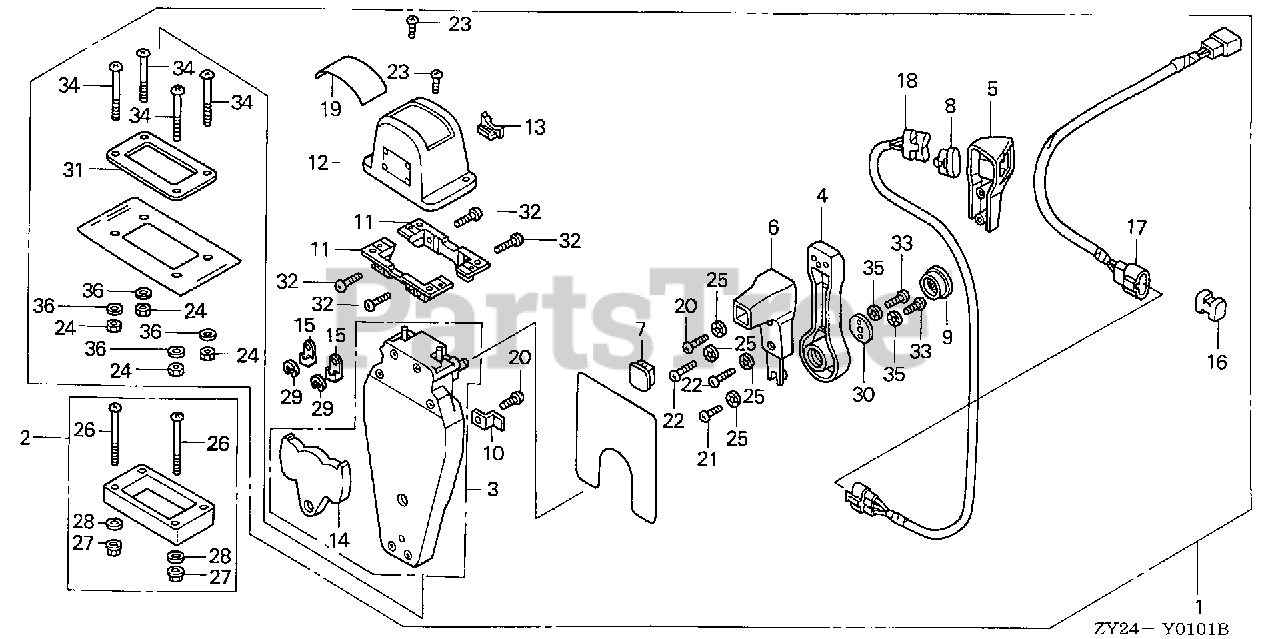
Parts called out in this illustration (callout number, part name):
1	BOX KIT, REMOTE CONTROL (TOP MOUNT SINGLE)(L)
2	SPACER KIT, REMOTE CONTROL BOX (TOP MOUNT SINGLE)
3	HOUSING ASSY., R. (INNER) (TOP MOUNT)
4	HANDLE, REMOTE CONTROL
5	COVER, R. GRIP
6	GRIP, REMOTE CONTROL HANDLE
7	CAP, GRIP
8	CAP, SWITCH
9	BUTTON, THROTTLE
10	PLATE, CABLE CLAMP
11	BRACKET, REMOTE CONTROL HOUSING
12	HOUSING, REMOTE CONTROL BOX
13	HOUSING, LEAD
14	PLATE, DWELL
15	TERMINAL, CABLE
16	SPACER, CABLE CLAMP
17	SUB-HARNESS ASSY., POWER TRIM-TILT (B)
18	SWITCH ASSY., POWER TRIM-TILT (B)
19	MARK, REMOTE CONTROL (SINGLE)
20	SCREW, PAN (5X16)
21	SCREW, PAN (5X10)
22	SCREW, PAN (5X20)
23	SCREW, PAN (4X10)
24	NUT, HEX. (5MM)
25	WASHER, LOCK (5MM)
26	SCREW, PAN (5X65)
27	NUT, FLANGE (5MM)
28	WASHER, PLAIN (5MM)
29	E-RING (6MM)
30	PLATE, HANDLE
31	GASKET, SINGLE
32	SCREW, PAN (5X18)
33	SCREW, PAN (6X18)
34	SCREW, PAN (5X40)
35	WASHER, LOCK (6MM)
36	WASHER, PLAIN (5MM)
